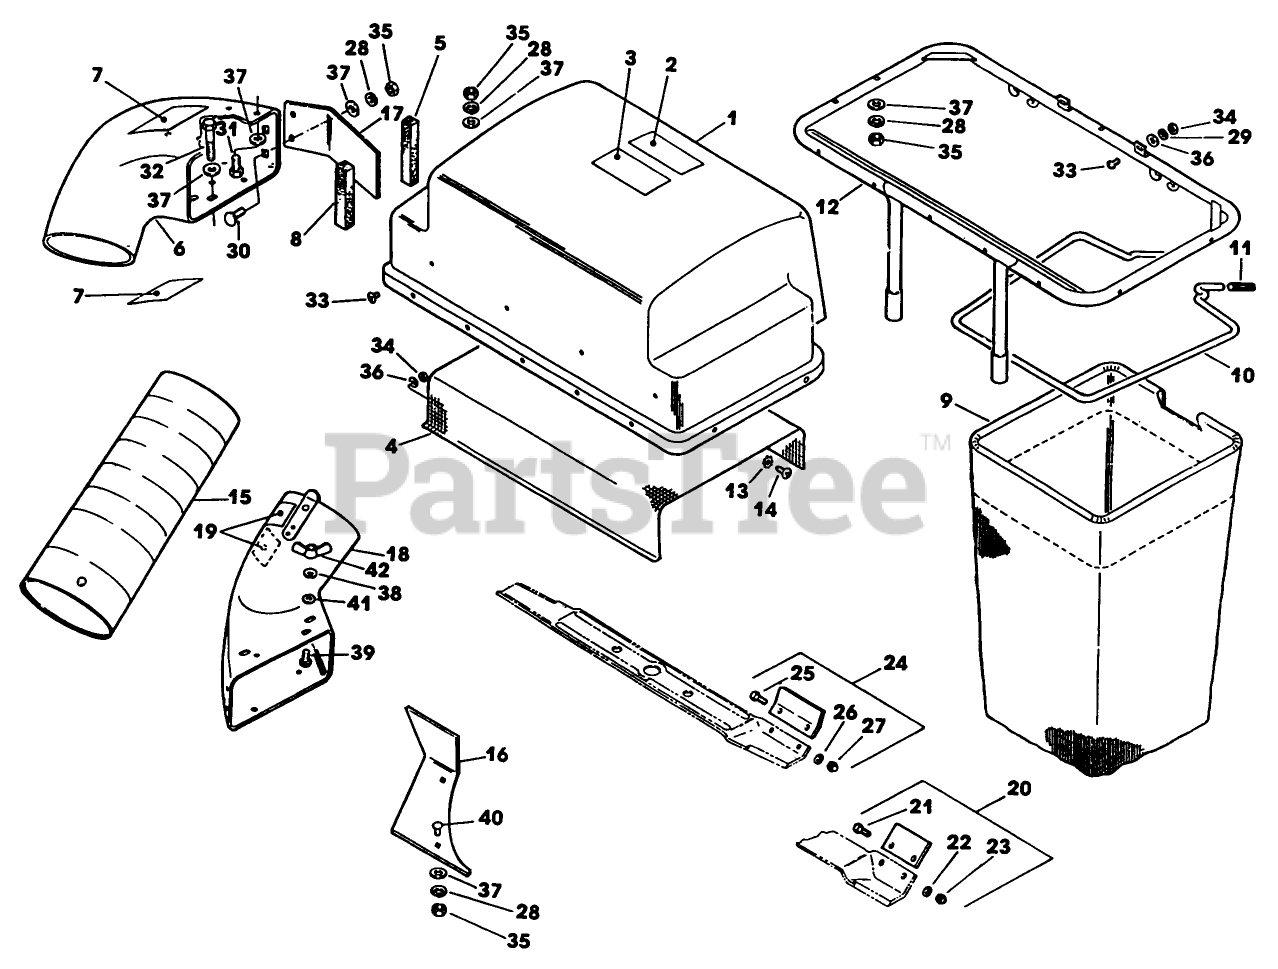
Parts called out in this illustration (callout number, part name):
1	COVER & STICKER AY
9	GRASS BAG
10	FRAME-GRASS BAG
16	DEFLECTOR-CHUTE
17	DEFLECTOR - GRASS
21	SCREW - HEX
23	NUT
24	BLADE EXTSN KIT
25	SCREW - HEX
27	NUT
35	NUT
39	BOLT - CARRIAGE
